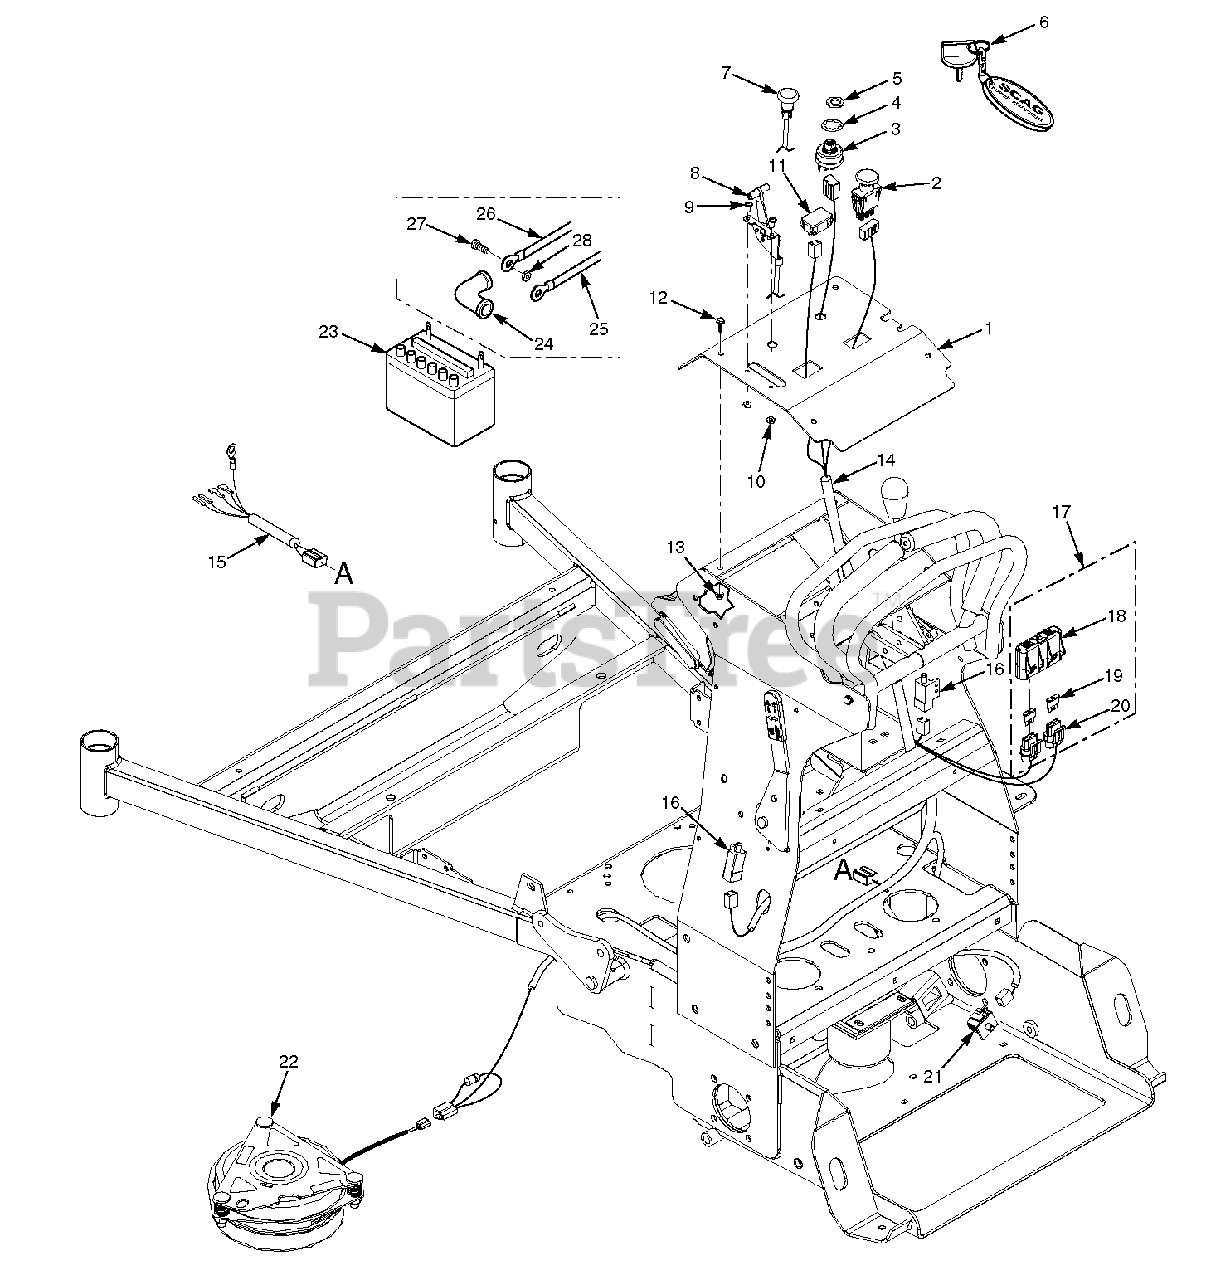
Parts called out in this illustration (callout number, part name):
1	Instrument Panel w/Decal
2	Switch, PTO - 10 Amp
3	Key Switch
4	Lockwasher, 5/8" Internal Tooth
5	Nut, 5/8-32 Special
6	Key Chain w/ Keys
7	Choke Control, SVR
8	Throttle Control, SVR
9	Bolt, Carriage #10-24 x 1/2"
10	Locknut, #10-24
11	Hourmeter
12	Bolt, Hex Head 1/4-20 x .63
13	Nut, Serrated Flange 1/4-20
14	Wire Harness, SVR
15	Wire Harness Adapter
16	Switch, Interlock
17	Double Fuse Assy.
18	Cover, Sealed Double
19	Fuse, 20 Amp
20	Fuse Holder
21	Switch, Double Pole - Plunger
22	Clutch w/Tag
23	Battery
24	Rubber Boot
25	Cable, Battery Black 18"
26	Cable, Battery Red 18"
27	Bolt, Hex Head 1/4-20 x 3/4"
28	Nut, 1/4-20
